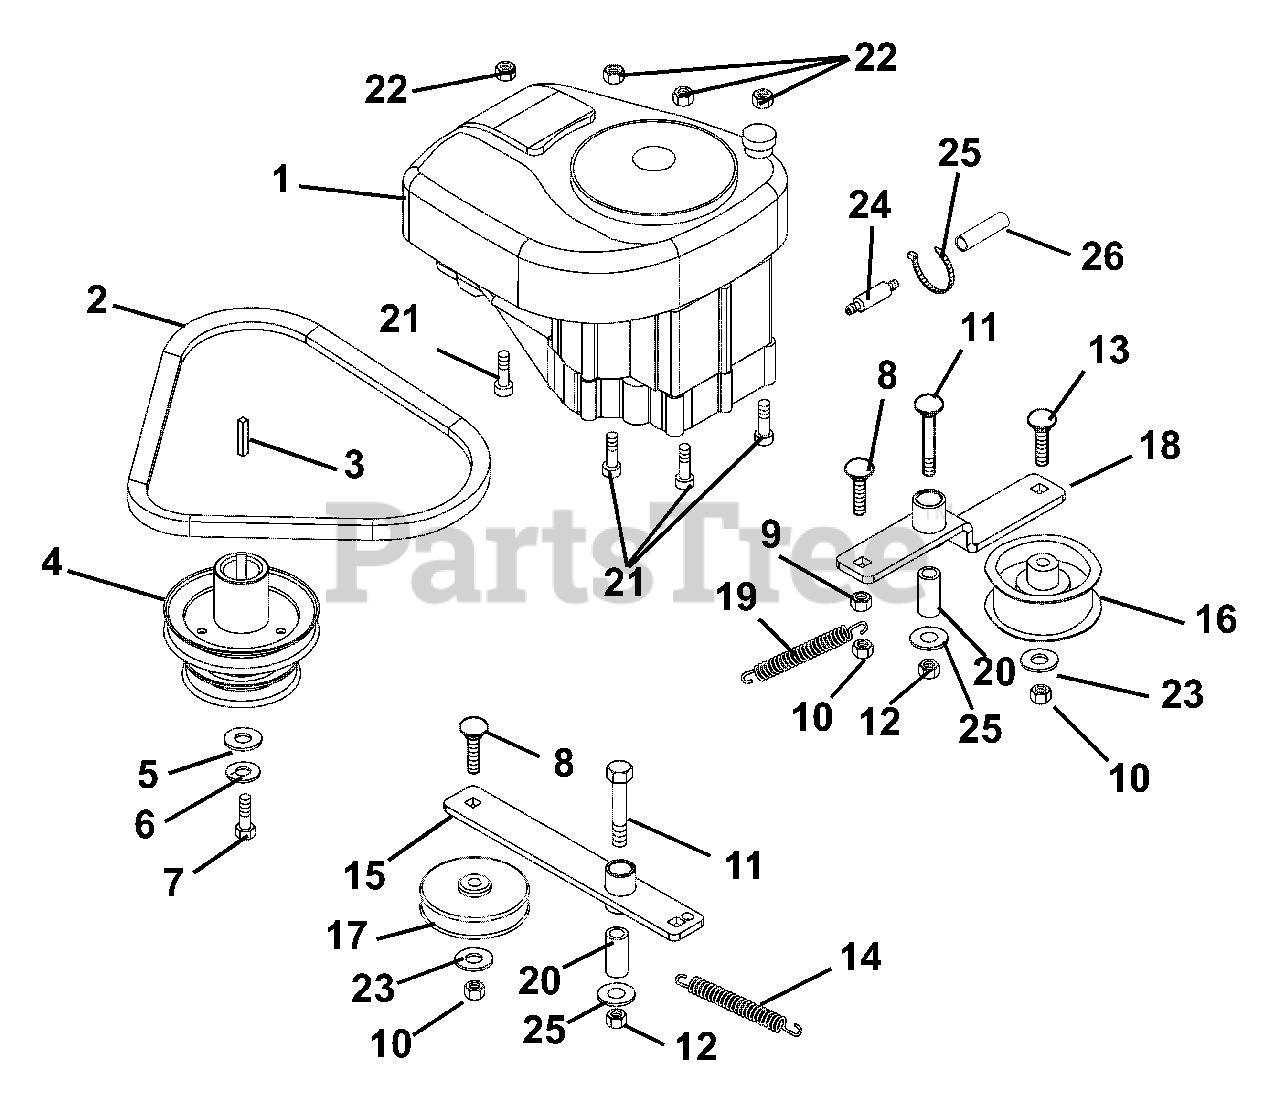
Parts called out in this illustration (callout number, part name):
1	Engine, Briggs & Stratton Model 21, 10.5HP (066)
1	Engine, Briggs & Stratton Model 28, 14.5HP (068)
2	V-Belt 4L-Section 30.219 x .547
3	Key, Straight .25 x 1.75 x .25
4	Stack, Sheave (066, 068)
5	Washer, Flat Steel
6	Washer, Locking .44 x .109 Regular
7	Bolt, Hex .44-20 x 1.75 Grade 5
8	Bolt-Round Head Square Neck .38-16 x 1.25 Grade 5
9	Nut-Flange .375-16
10	Nut, Locking Top Flange .38-16
11	Bolt, Hex .50-13 x 2.25 Grade 5
12	Nut, Locking Nylock Thin .50-13
13	Bolt-Round Head Square Neck .38-16 x 2.00 Grade 5
14	Spring, Tension .095 x .50 x 5.50
15	Idler, Drive
16	Sheave, 3.25 x 1.25
17	Idler, V 3 x .38
18	Idler, 32" Deck PTO
19	Spring, Extension.093 x .75 x 4.00
20	Bushing-Sleeve .50 x .75 x 1.56
21	Screw, Socket Head Button Head .31-18 x 1.50 Grade 8
22	Nut-Locking-Top-Flange .31-18
23	Washer-Flat-Steel .38 x .875 x .083
24	Valve, Oil Drain
25	Cable Tie
26	Tube, Oil Drain
27	Washer-Flat-Steel .563 x 1.38 x .109
